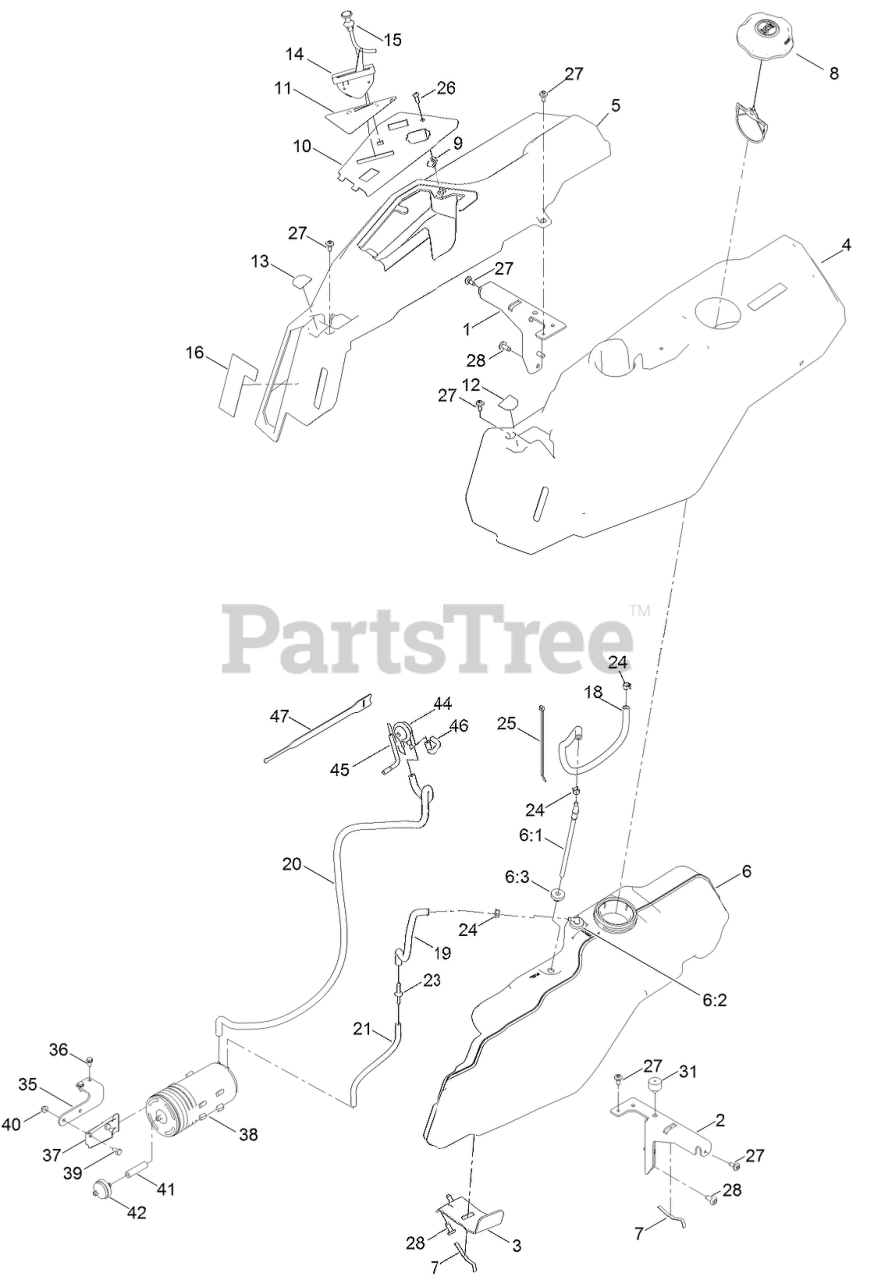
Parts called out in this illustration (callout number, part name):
1	SUPPORT-POD, RH
2	SUPPORT-POD, LH
3	SUPPORT-TANK, FUEL
4	POD-LH
5	POD-RH
6	FUEL TANK ASM
6:1	CONNECTOR-ELBOW, 90 DEG
6:2	FITTING-PLASTIC
6:3	BUSHING
7	SPRING
8	CAP-FUEL, RATCHETING
10	PANEL - CONTROL
11	DECAL-PANEL, CONTROL
12	DECAL-CONTROL LEVER, LH
13	DECAL-CONTROL LEVER, RH
14	CABLE-THROTTLE
15	CABLE-CHOKE
16	DECAL-SMART SPEED
18	HOSE-FUEL
19	HOSE-FUEL
20	HOSE-FUEL
21	HOSE-FUEL
23	ADAPTOR-ORIFICE
24	CLAMP-HOSE
25	TIE-CABLE
26	SCREW-PRH
27	SCREW-SHOULDER
31	BUMPER-GROMMET
35	BRACKET-CANISTER, CARBON
36	SCREW-HWH
37	BRACKET-CANISTER, CARBON
38	CANISTER-CARBON, 800CC
39	SCREW-HH
40	NUT-HF
41	HOSE-FUEL
42	FILTER-FUEL, INLINE
44	VALVE-CONTROL, VACUUM
45	HOSE-VENT, FORMED
46	HOSE-VENT, FORMED
47	STRAP-VELCRO, CABLE TIE
